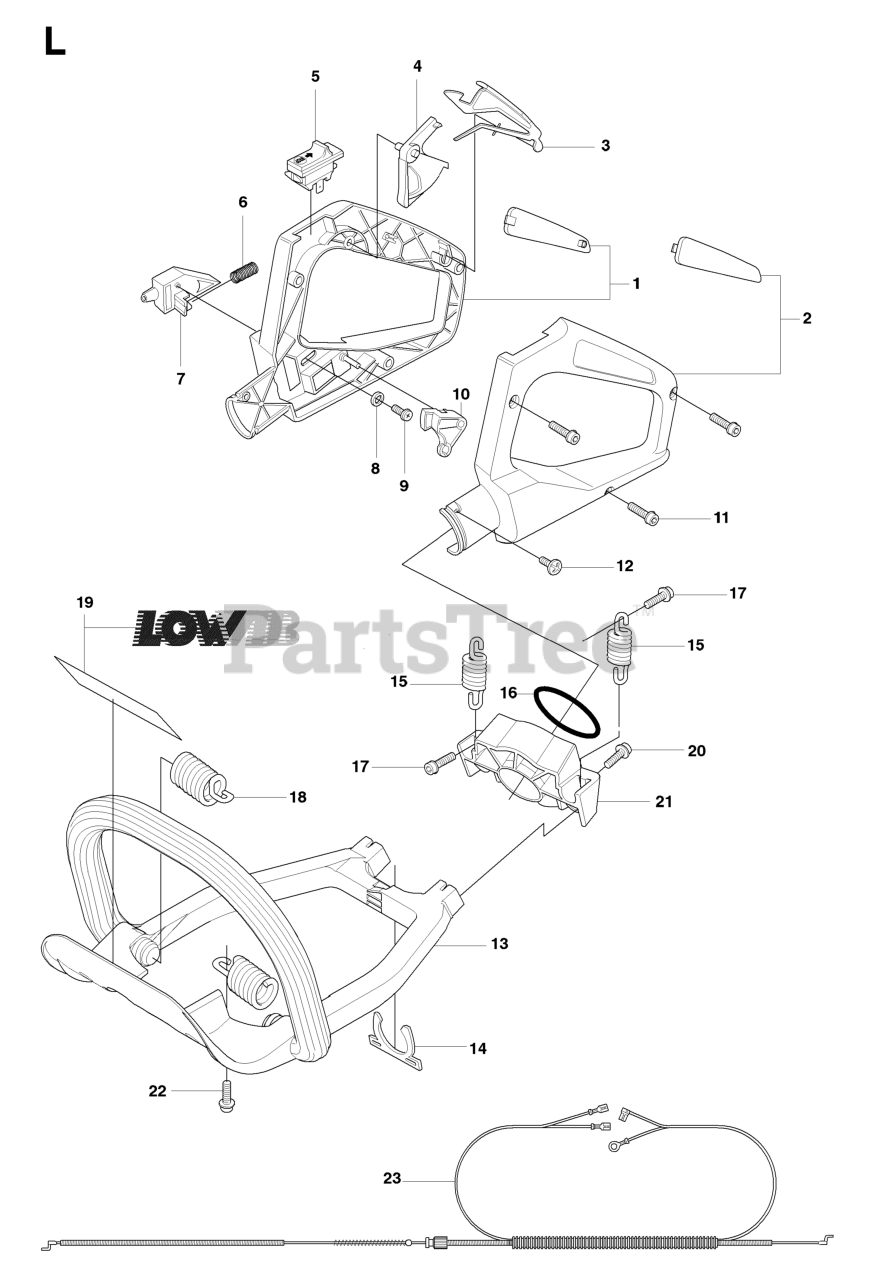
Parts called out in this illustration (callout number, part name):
1	HANDLE PART
2	HANDLE PART
3	THROTTLE LOCK
4	THROTTLE TRIGGER
5	STOP BUTTON
15	VIBRATION ABSORBER
18	VIBRATION ABSORBER
23	WIRING
